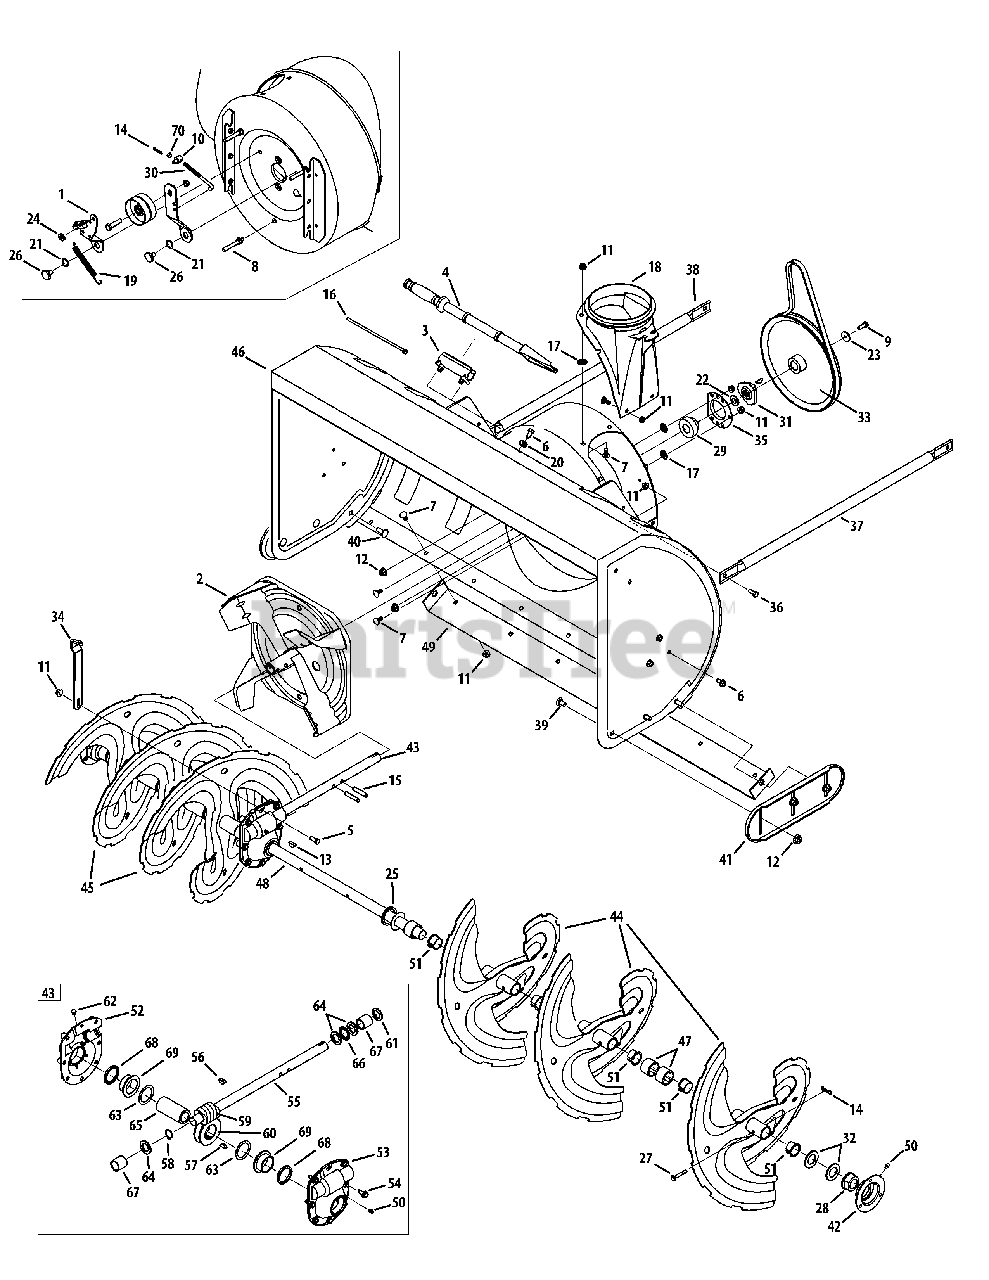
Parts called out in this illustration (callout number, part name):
1	Bracket Assembly, Auger Brake
2	Impeller , 16"
3	Clip, Mounting
4	Tool, Clean-out
5	Screw, Hex Cap, 5/16-18 x 1.0 Gr5
6	Screw, 5/16-18 x .750
7	Screw, Carriage, 5/16-18 x .75
8	Screw w/Stud, 5/16-18 x .4300
9	Screw, Hex Cap Lock, 5/16-24, 875
11	Nut, Hex Flange Lock, 5/16-18
12	Nut, Hex Flange Lock, 3/8-16
13	Key, Woodruff, 1/4 x 3/4
14	Pin, Bow-tie Cotter
15	Pin, Spiral, 5/16 x 1.75
16	Cable Tie
17	Nut, Push
18	Adapter, Chute, 6"
19	Spring, Extension
20	Washer, Flat, .349 x .879 .063
21	Washer, Wave, .625 x .885 x .015
22	Washer, Bell., .78 x 1.49 x .06
23	Washer, Flat, .34 x 1.5 x .15 Ht.
24	Washer, .344 x .75 x .12
25	Washer, 1.01 x 1.86 x .06
26	Screw, Shoulder, .625 x .17
27	Pin, Shear, .25 x 1.75
28	Bearing, Flange w/Flats
29	Bearing, Self Aligning
30	Rod, Auger Idler
31	Adapter, Pulley w/Pins
32	Spacer, 1.004 x 1.375 x .25
33	Pulley, Auger Drive, 10.0
34	Bracket, Gear Box Support
35	Housing, Bearing
36	Screw, 5/16-18 x .75 GR5
37	Tube, Support , LH
38	Tube, Support, RH
39	Screw, Carriage, 3/8-16 x .75
40	Screw, Carriage, 3/8-16 x 1.00
42	Housing, Bearing
43	Gear Box Assembly
44	Spiral Assembly, LH
45	Spiral Assembly, RH
46	Housing, Auger - 45"
47	Spacer, 1.50 x 1.00 x 1.00
48	Axle, Spiral
49	Shave Plate, 45"
50	Grease Fitting, 3/16
51	Flange Bushing
52	Housing Assembly, Auger, RH
53	Housing Assembly, Auger, LH
54	Screw, LD, 5/16-18 x .750
55	Auger Drive Shaft
56	Key, Hi Pro, 3/16 x 3/4
57	Key, 1/4 x 3/4 Dia.
58	External Retainer Ring
59	Gear, Worm
60	Gear, Worm, LH
61	Seal, Oil
63	Wash, Flat, 1.52ID x 2.0 OD
64	Wash, Flat, .88 ID x .38 OD
65	Worm Gear Shaft
66	Bearing, Thrust
69	Flange Bearing
70	Jam Nut, 5/16-18
